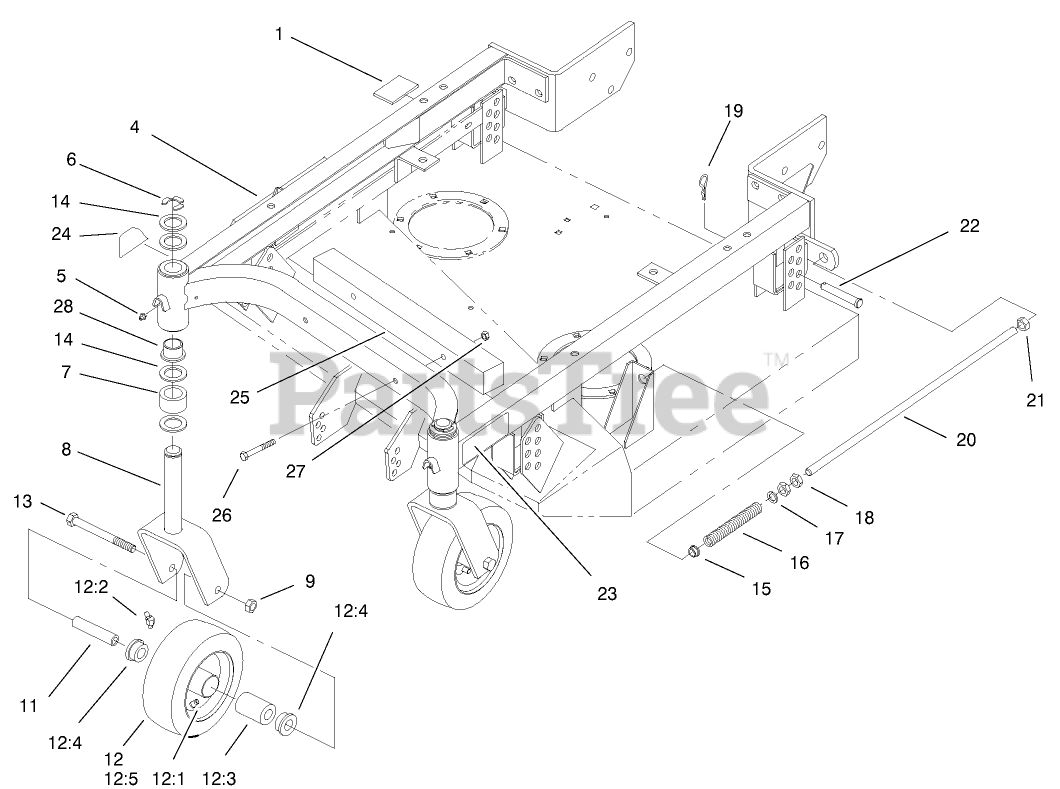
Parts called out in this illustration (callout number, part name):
1	CUSHION-RUBBER
4	36" Carrier Frame
5	FITTING-GREASE
6	Pin
7	SPACER-CASTOR
8	CASTOR FORK ASM
9	NUT-HEX
11	BUSHING-SPANNER
12	CASTER WHEEL ASM
12:1	STEM-VALVE
12:2	FITTING-LUBE, 45 DEG
12:3	BEARING
12:4	BEARING-OUTSIDE
12:5	TIRE-TUBELESS
13	SCREW-HH
14	WASHER-THRUST
15	BUSHING-FLANGE
16	SPRING
17	WASHER
18	NUT-JAM
19	PIN-HAIR
20	SHAFT-ADJUSTING
21	NUT-LOCK, NI
22	PIN-CLEVIS
23	DECAL-HOC, LH
24	DECAL-HOC, RH
25	Front Weight
26	SCREW-HH
27	NUT-LOCK, NI
28	BUSHING
